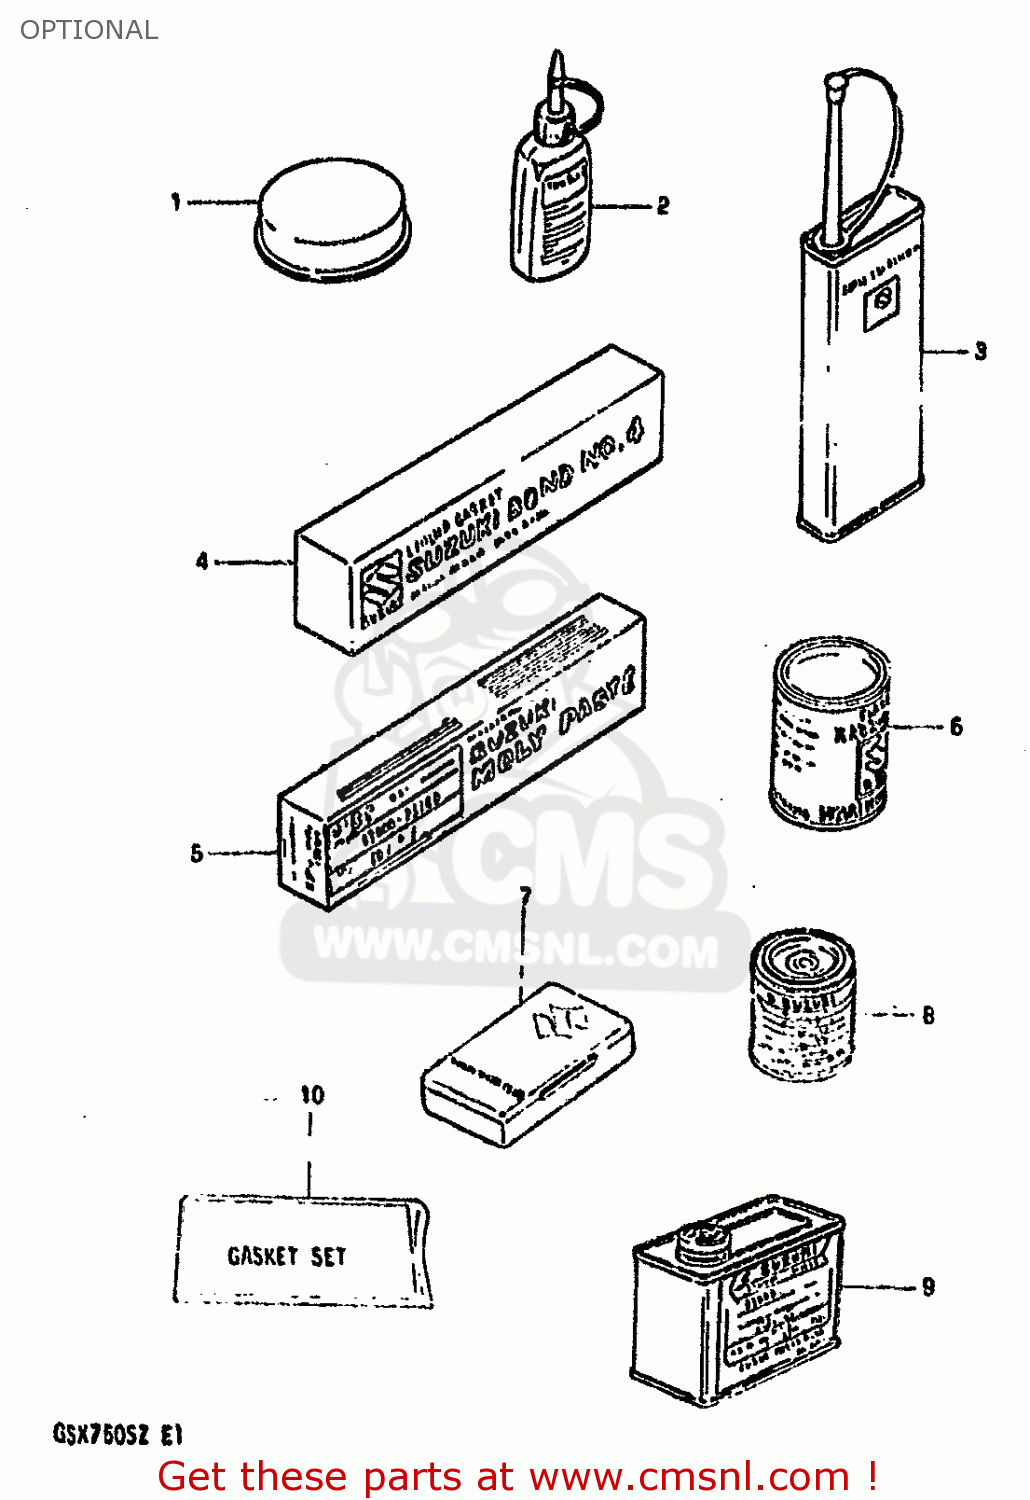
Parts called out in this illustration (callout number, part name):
1	GREASE,PBC FOR BRK PAD 20G
2	THREAD LOCK SUPER (1332B)
3	THREAD LOCK NO.1401 CLEAR 200G
4	BOND 1104
5	SUZUKI MOLY PASTE
6	GREASE(C)EP2 LITHIUM 150G
7	TUBE REPARING TOOL
8	PAINT,BLACK
9	PAINT (MABLE SAINT RED)
10	GASKET SET
